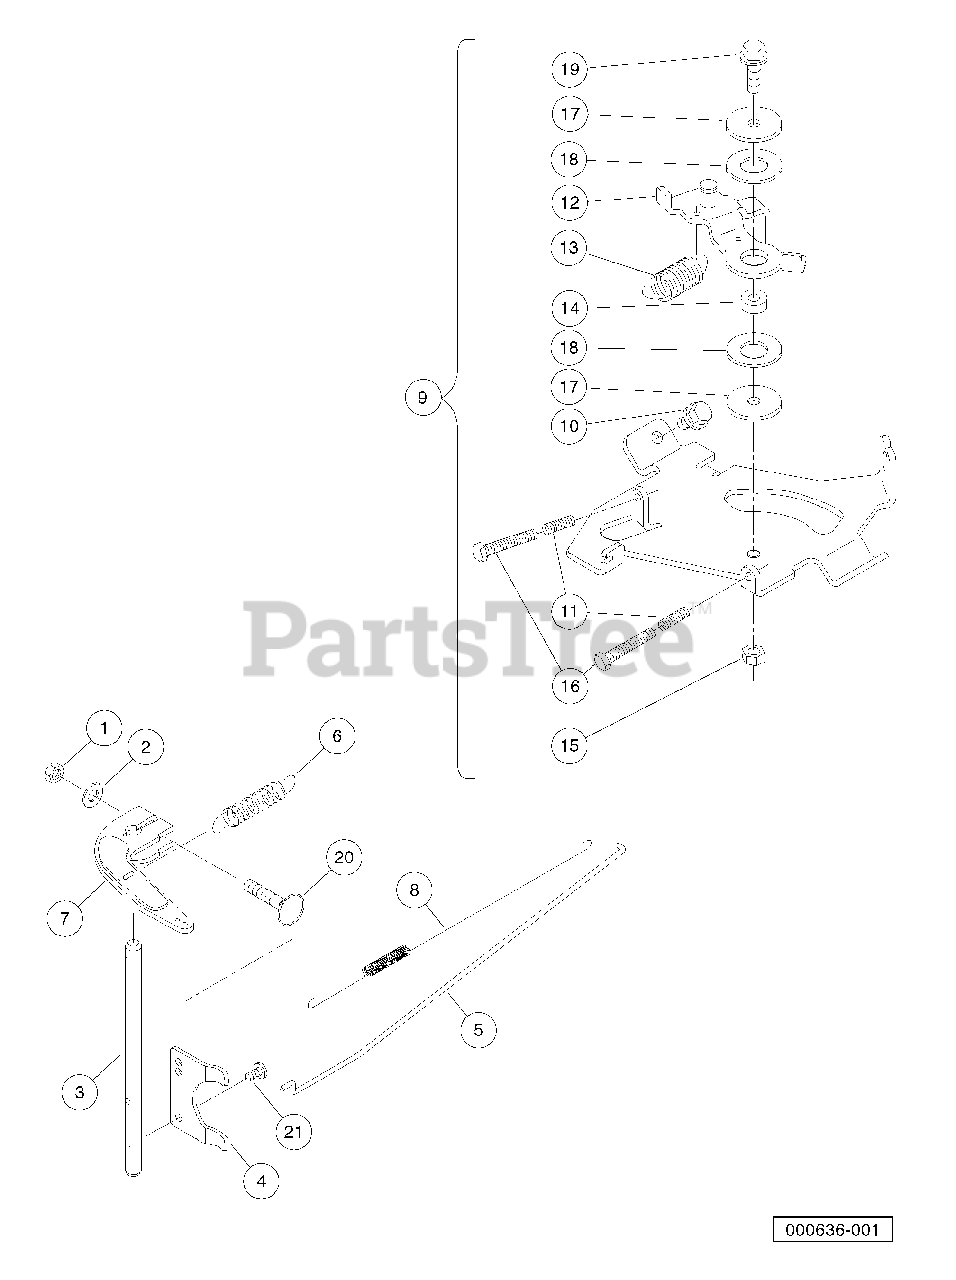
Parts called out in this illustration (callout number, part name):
1	Nut -6mm-
2	Washer, M6 Flat
3	Shaft, Governor, Fh
4	Plate, Governor, Fh
5	Link, Arm, Governor, Fh
6	Spring, Governor, Fh
7	Arm, Governor, Shaft
8	Spring, Arm, Governor, Fh
9	Panel, Control, Complete, Fh
10	Bolt, Flg, M6 X 1.0 X 12
11	Spring, Fh
12	Lever, Governor, Control, Fh
13	Spring, Governor Return, Fh
14	Collar, Governor, Fh
15	Nut, Governor, Fh
16	Bolt, Speed Control, Fh
17	Washer, Governor, Lower, Fh
18	Washer, Governor, Middle, Fh
19	Bolt, Flanged, M6 X 20, Kaw
20	Bolt, M6 X 35, Kawasaki
21	Screw, Pan, Governor, Fh
